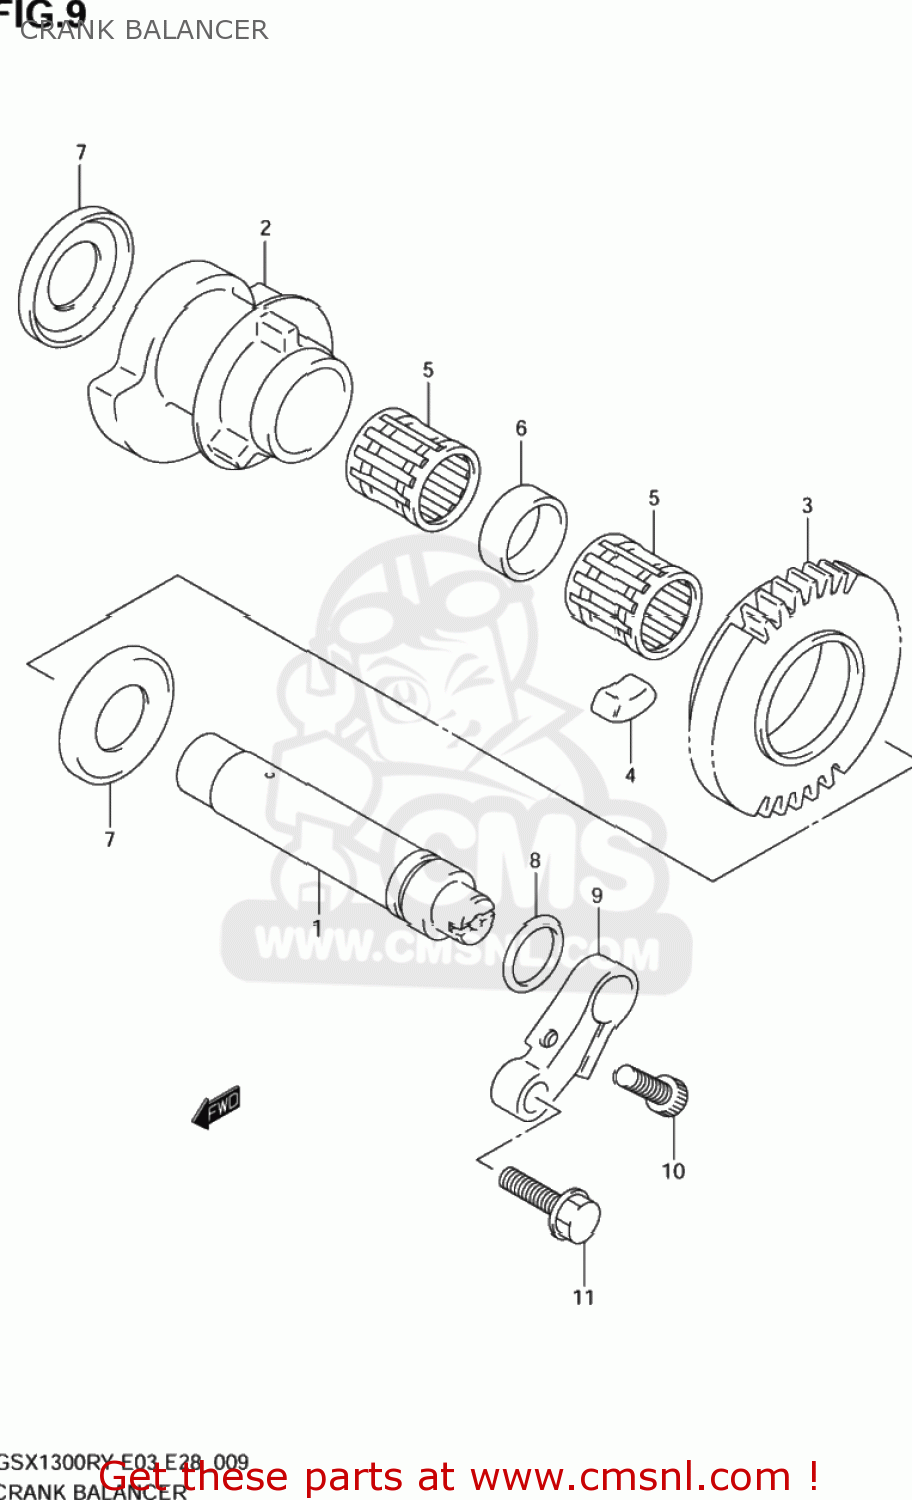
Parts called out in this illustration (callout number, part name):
1	SHAFT COMP,CRANK BALANCER
2	BALANCER,CRANK
3	GEAR,CRANK BALANCER
4	DAMPER,BALANCER GEAR
5	BEARING(19X26X25.2)
6	SPACER(19X26X8.6)
7	WASHER
8	O RING(D:1.9,ID:16.6)
9	ARM,BALANCER SHAFT
10	BOLT,CRKCASE,R
11	BOLT 6X20
